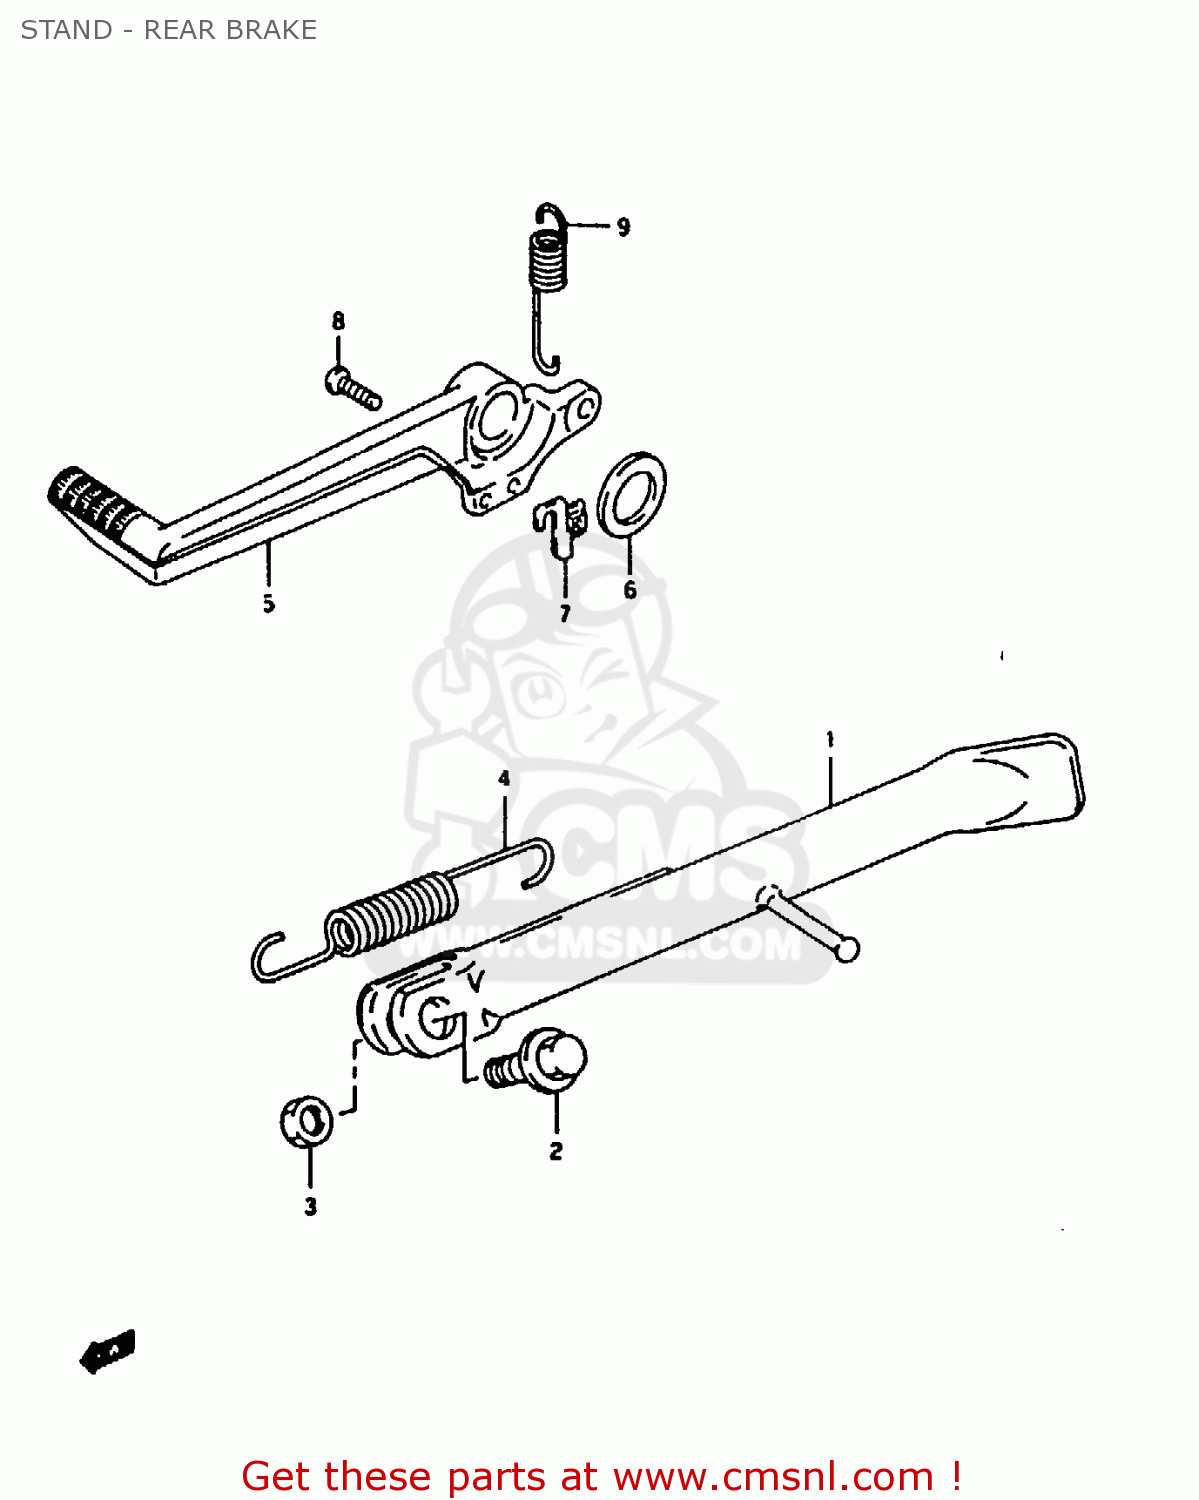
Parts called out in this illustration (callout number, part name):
1	STAND,PROP
2	BOLT(10X30)
3	NUT
4	SPRING
5	PEDAL, BRAKE
6	WASHER(18X24X1)
7	BRACKET, SPRING
8	SCREW
9	SPRING
